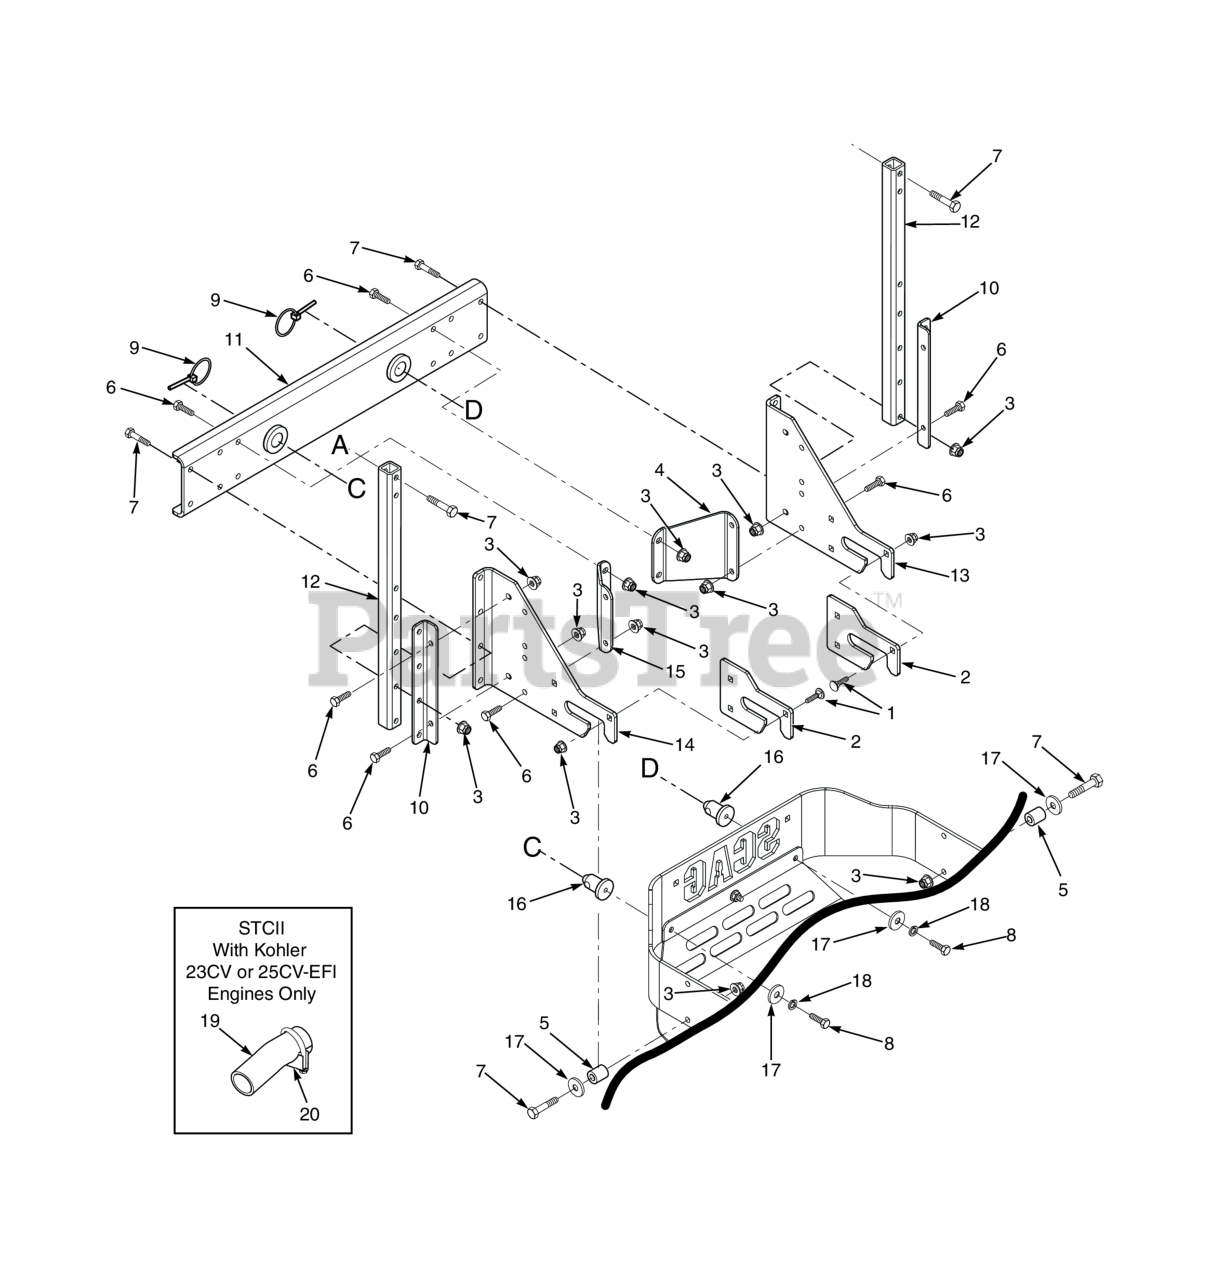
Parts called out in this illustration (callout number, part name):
1	Carriage Bolt, 3/8-16 x 1-1/4"
2	Wear Plate, GC
3	Nut, Flange Elastic Stop Nut, 3/8-16
4	Angle Bracket, GC
5	Spacer
6	Bolt, Hex Head 3/8-16 x 1"
7	Bolt, Hex Head 3/8-16 x 2-1/4" - 61"
8	Bolt, Hex Head 3/8-16 x 1-1/4", Kawasaki FX / FT & FT-EFI
9	Quick Pin, 5/16" Dia.
10	Mounting Bracket, Tube
11	Mounting Bracket Weldment
12	Tube, Upright
13	Mounting Bracket, GC R.H.
14	Mounting Bracket, GC L.H.
15	Angle Bracket, GC
16	Pin, GC Locator
17	Flatwasher, 3/8-.406 x 1-1-1/2 x 7 Gauge
18	Lockwasher, 3/8" Spring, Kawasaki FX / FT & FT-EFI / B&S 32BV
19	TUBE, EXHAUST
20	Clamp, Muffler (Clamp Only)
